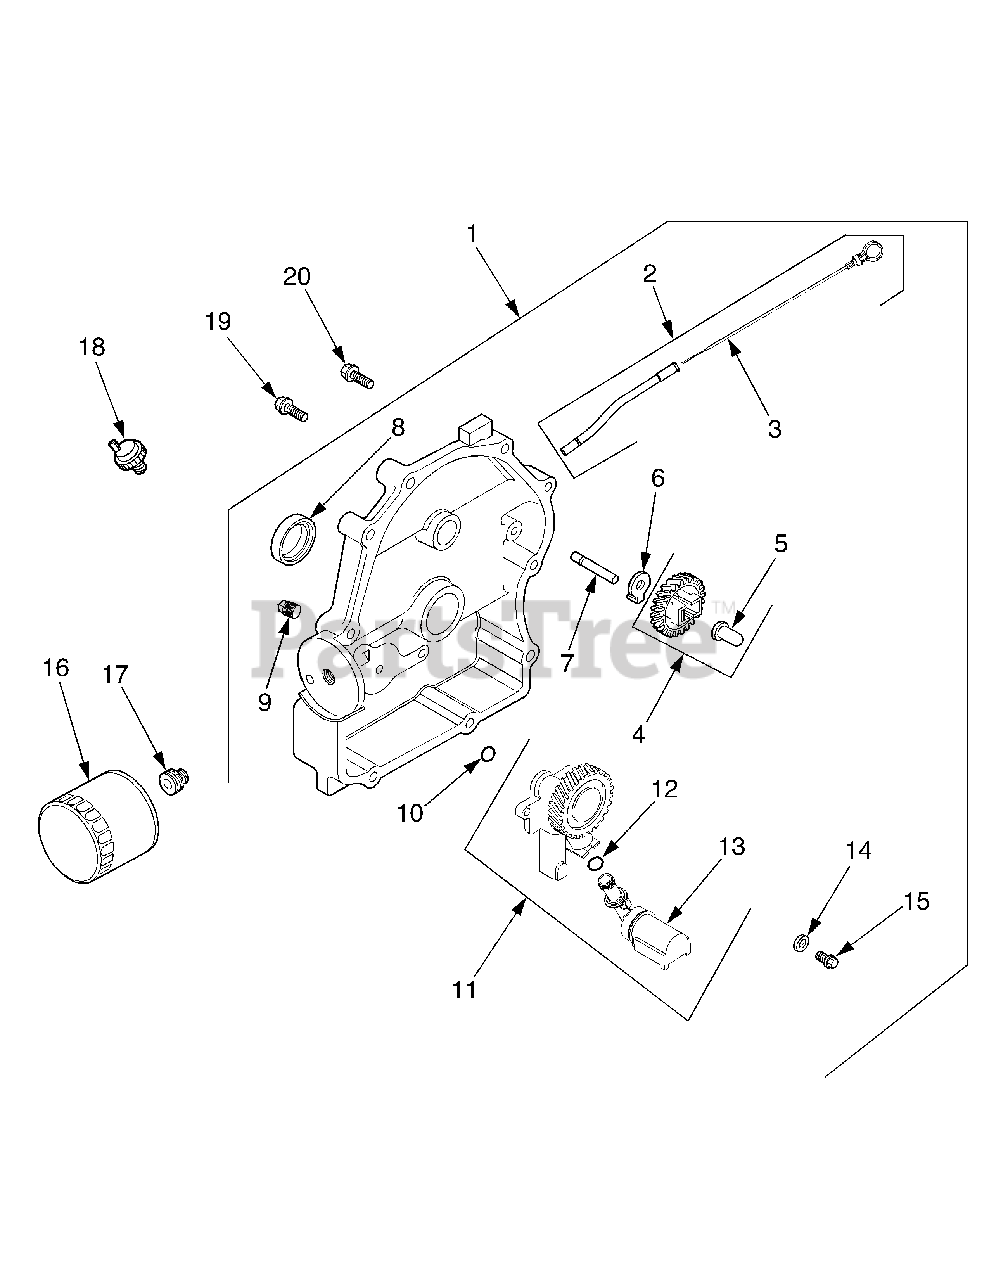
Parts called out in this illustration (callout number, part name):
1	Plate, Closure Assembly (Includes 2-15)
2	Tube, Dipstick (Includes 2)
4	Kit, Governor Gear (Includes 5) ..
5	Pin, Governor Regulating
7	Shaft, Governor Gear
8	Seal, Oil (PTO End)
9	Plug, Pipe 1/8"
11	Oil Pump Assembly (Includes 12,13)
12	O-Ring, Oil Pick-Up
13	Pick-Up, Oil
14	Washer, Plain
15	Screw, Hex Flange M6 x 1 x 25 ..
16	Filter, Oil
17	Nipple, Oil Filter
18	Switch, Pressure
19	Screw, Hex Flange M8 x 1.25 x 45
20	Screw, Hex Flange M8 x 1.25 x 45
